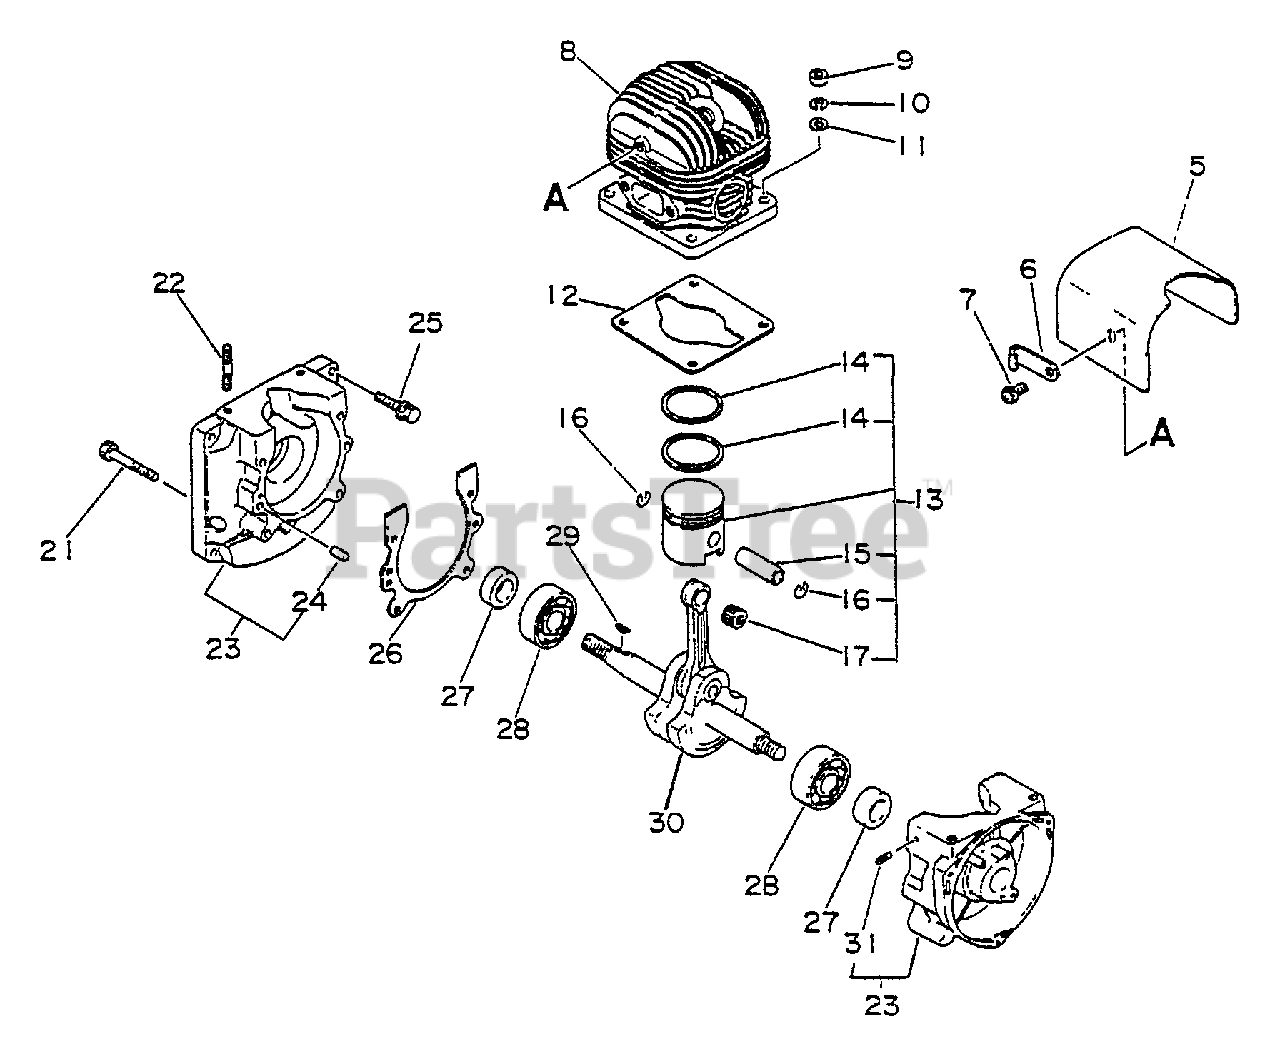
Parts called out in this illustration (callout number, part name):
5	COVER, CYLINDER
7	BOLT - 6×10
8	CYLINDER
9	NUT, HEX M6
10	WASHER, SPRING 6
11	WASHER 6.5×11.5×0.8
12	GASKET, CYLINDER
13	PISTON KIT
14	RING, PISTON
15	PIN, PISTON
16	RING, SNAP 8
17	BEARING, NEEDLE
23	CRANKCASE KIT
24	PIN, LOCATING 5×10
25	BOLT - 5×25
26	GASKET, CRANKCASE
27	SEAL, OIL
28	BEARING, BALL 6202
30	CRANKSHAFT ASSY
31	CONNECTOR
